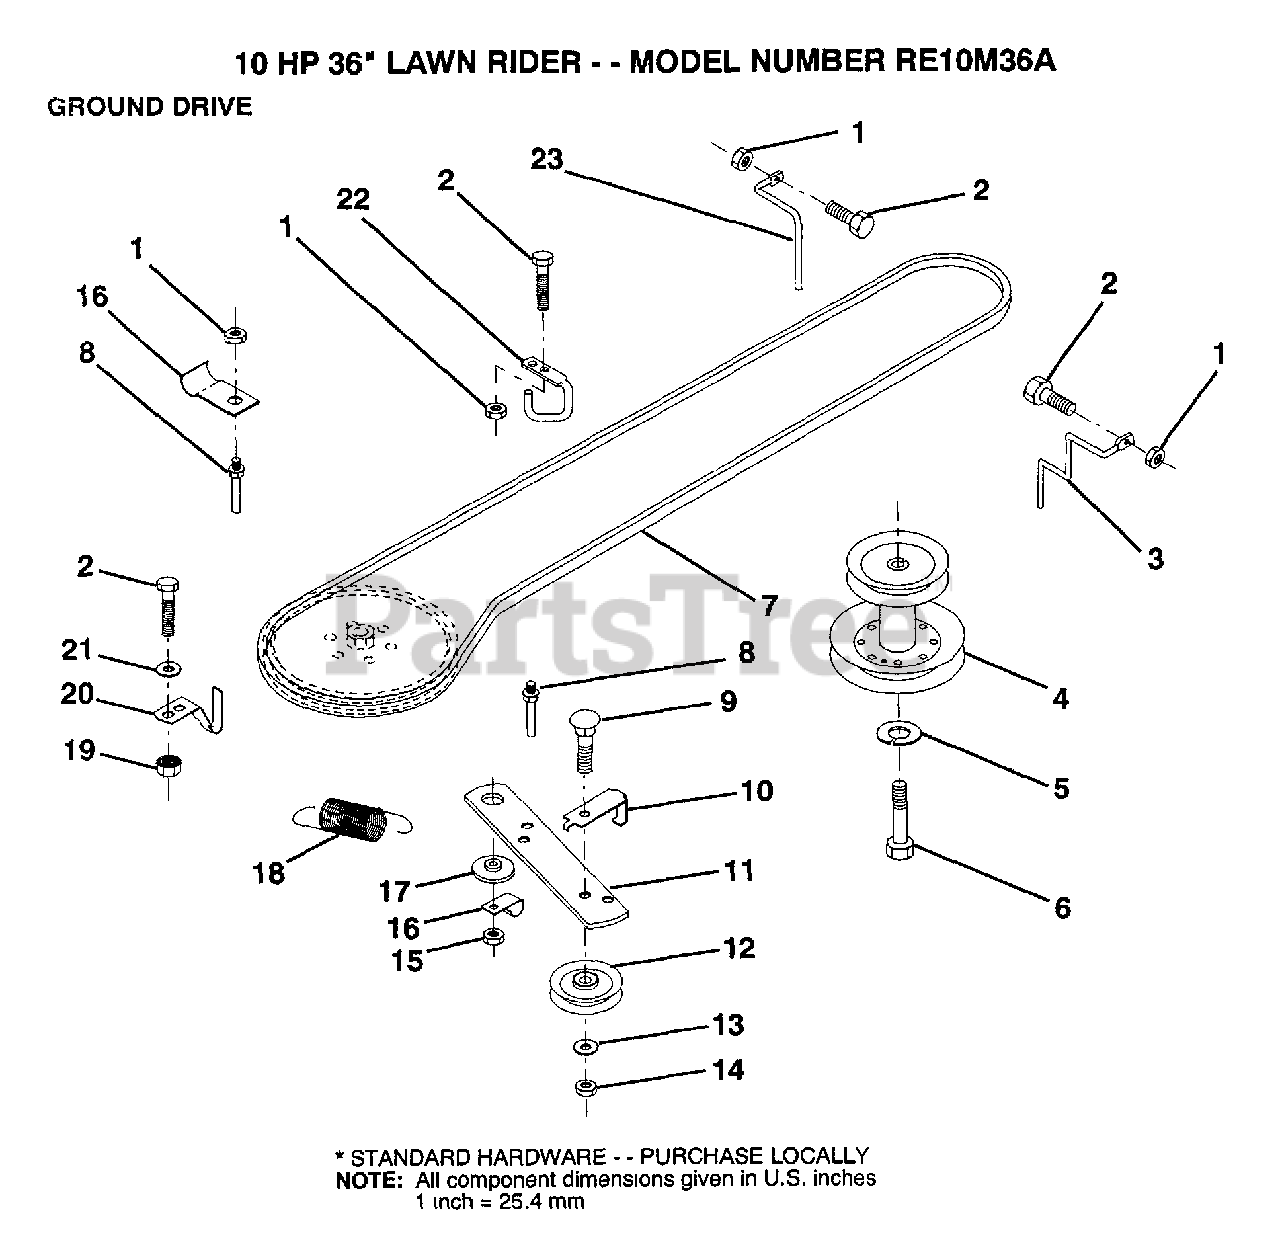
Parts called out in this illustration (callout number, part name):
2	BOLT
5	LOCKWASHER
6	HEX BOLT
7	BELT
8	"KEEPER,DRIVE BELT"
9	BOLT
10	"KEEP,IDLER DR BEL"
13	WASHER
14	LOCKNUT
16	"CLIP,INSULATOR"
17	SPACER RETAINER
20	"KEEPER,DR BELT "
21	WASHER
22	"KEEPER,FRA DR BEL"
